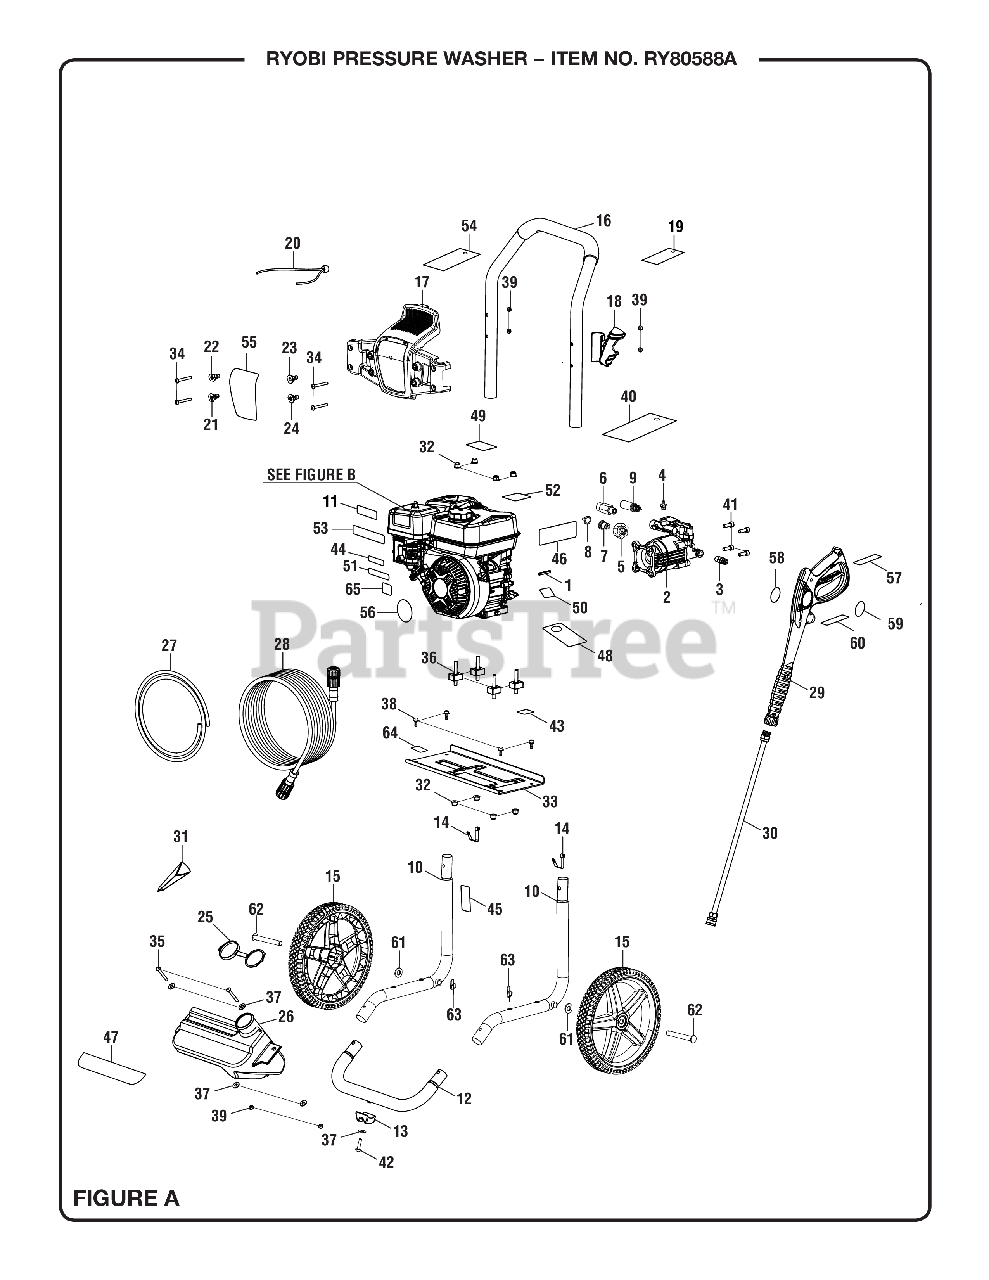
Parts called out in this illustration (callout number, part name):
1	Output Shaft Key (3/16 in. x 40 mm)
2	Pump
3	Thermal Release Valve.
4	Detergent Injector Assembly
5	Inlet Filter Adapter/Brass Insert
6	Outlet Tube
7	Inlet Filter Connector
8	Filter Screen (Pump Inlet)
9	Unloader Valve Assembly
10	Main Frame Assembly
11	EMC ICES-2/NMB-2 Label (Canada)
12	Front Frame Assembly
13	Rubber Foot
14	Lock Button w/Spring Clip.
15	Wheel
16	Handle Assembly
17	Hose and Nozzle Holder Assembly
18	Trigger Handle Holder
19	Quick Start Hangtag
20	Bungee Cord and Bead Assembly
21	0deg Nozzle
22	25deg Nozzle
23	40deg Nozzle
24	Soap Nozzle (Blue)
25	Detergent Tank Cap
26	Soap Tank
27	Chemical Siphon Tube
28	Hose (25 ft.)
29	Trigger Handle Assembly
30	Extension Wand
32	Lock Nut (M8 x 1.25 mm, Flange)
33	Engine Plate
34	Bolt (M6 x 48 mm, Button Hd.)
35	Screw (M6 x 1 x 48 mm, T30 Torx Pan Hd.)
36	Engine Isolator
37	Washer (1/4 in.)
38	Flange Bolt (M6 x 1 x 16 mm, Hex Hd.)
39	Lock Nut (M6 x 1)
40	Danger Hangtag
41	Screw (5/16-24 x 23 mm, Hex Soc. Cap Hd.)
42	Screw (M6 x 1.25in., T30 Torx Pan Hd.)
43	Oil Fill Location Label
44	Choke Label
45	UL Fire Warning Label Spark Arrestor)
46	Danger Label
47	Detergent Tank Label
48	Hangtag (Oil Dipstick)
49	No E85 Label
50	Engine Switch Label
51	Fuel Valve Label
52	Hot Surface and Exhaust Label
53	Inquires Label (Ryobi)
54	Nozzle Instructions Hangtag
55	Performance Label
56	Recoil Label
57	Label (Trigger Handle Warning, French & Spanish)
58	Label (Trigger Handle Logo)
59	Label (Trigger Handle Warning, English)
60	Trigger Handle Specifications Label
61	Washer (1/2 in.)
63	Hitch Pin
64	Warning Label
65	Choke/Fuel Valve Label
